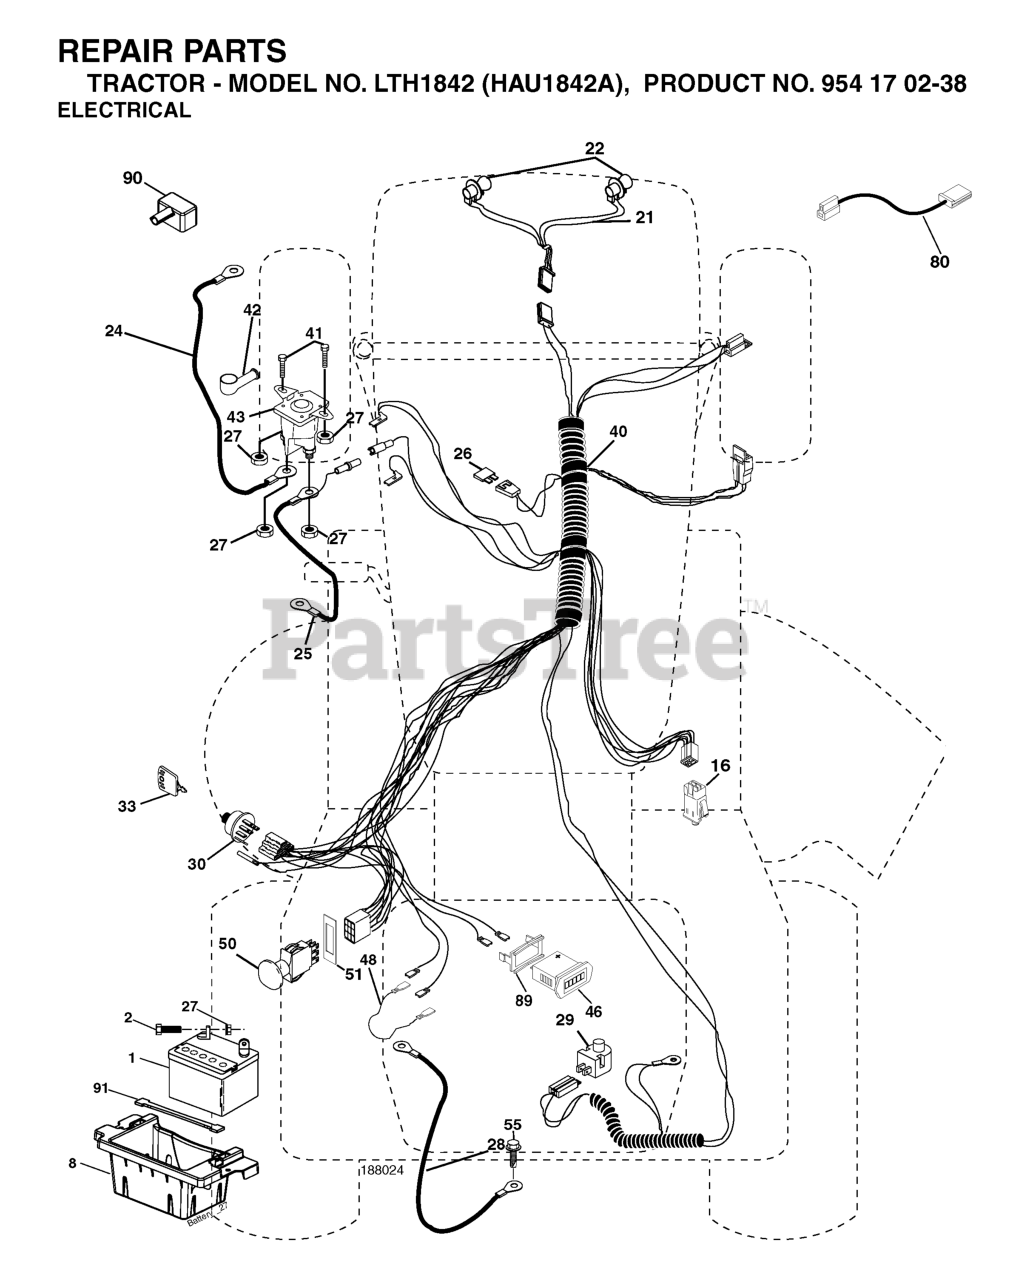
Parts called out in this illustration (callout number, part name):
1	BATTERY 12V .35 AMP
2	BOLT.HEX.1/4.X.3/4.DICHROMATE
8	BOX.BATTERY.MOUNT.FRONT.LT
16	SWITCH INTERLOOK PUSH-IN
21	HARNESS.W/LIGHT SOCKET
24	BATTERY CABLE GT
25	CABLE BATTERY 6 GA 22" W/16W
26	FUSE 20AMP
27	NUT
28	CABLE GROUND 6 GA 21" 90T BLK
29	RP.SWITCH.PLUNGER.NC.GRAY
30	IGNITION SWITCH
33	KEY MLD GEN DELTA
40	HARNESS.IGNITION
41	BOLT
42	TERMINAL COVER
43	SOLENOID
46	HOUR METER
48	ADAPTER.AMMETER
50	RP.PTO.SWITCH.8 TERMINAL.BLACK
51	FRAME RETAINING RING
55	Screw 5/16-18 x 1/2 Hex, Self Tapping 5/16-18 x 1/2
80	HARNESS, CLUTCH
89	BRACKET SNAP-IN HOURMETER
90	COVER TERMINAL
91	STRAP.BATTERY.MOUNT.FRONT(2 2)
